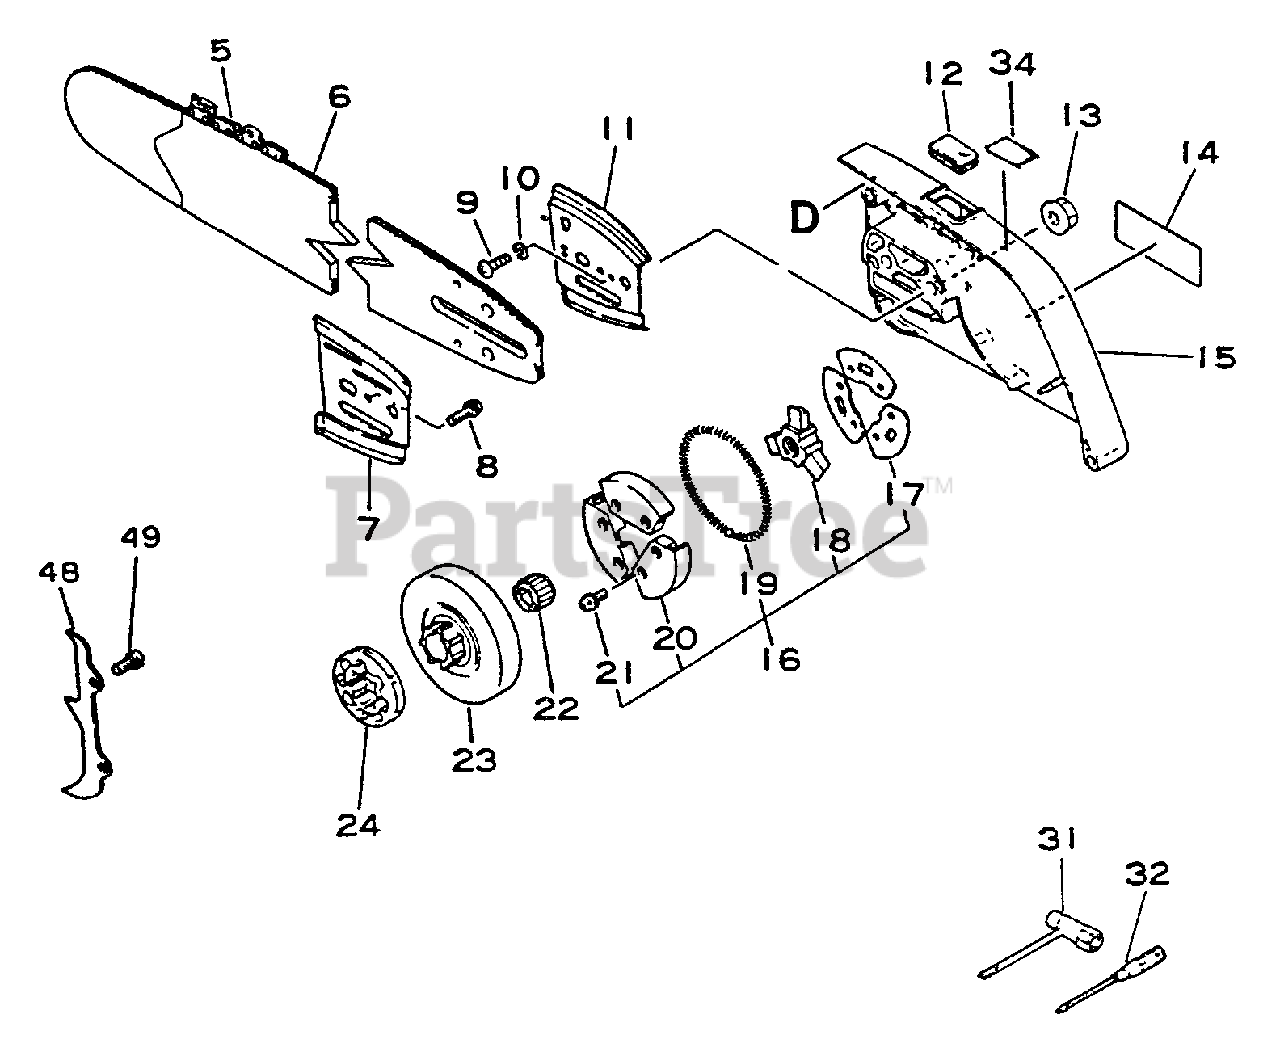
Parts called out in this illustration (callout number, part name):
6	GUIDE BAR
7	PLATE, GUIDE
8	SCREW - 4×8
9	SCREW 3×6
10	LOCKWASHER - 3
11	PLATE, GUIDE
13	NUT, FLANGE M8×1.25
14	LABEL - ECHO
15	GUARD, SPROCKET
16	CLUTCH ASSY
17	PLATE, CLUTCH
18	HUB, CLUTCH
19	SPRING, CLUTCH
20	SHOE SET, CLUTCH (3PCS)
21	SCREW - 4×8
22	BEARING, NEEDLE
23	DRUM, CLUTCH
24	SPROCKET, 0.325 RIM
25	LABEL, CAUTION
31	T-WRENCH 13×19×180
32	SCREWDRIVER, PHILLIPS
48	SPIKE KIT, BUMPER
